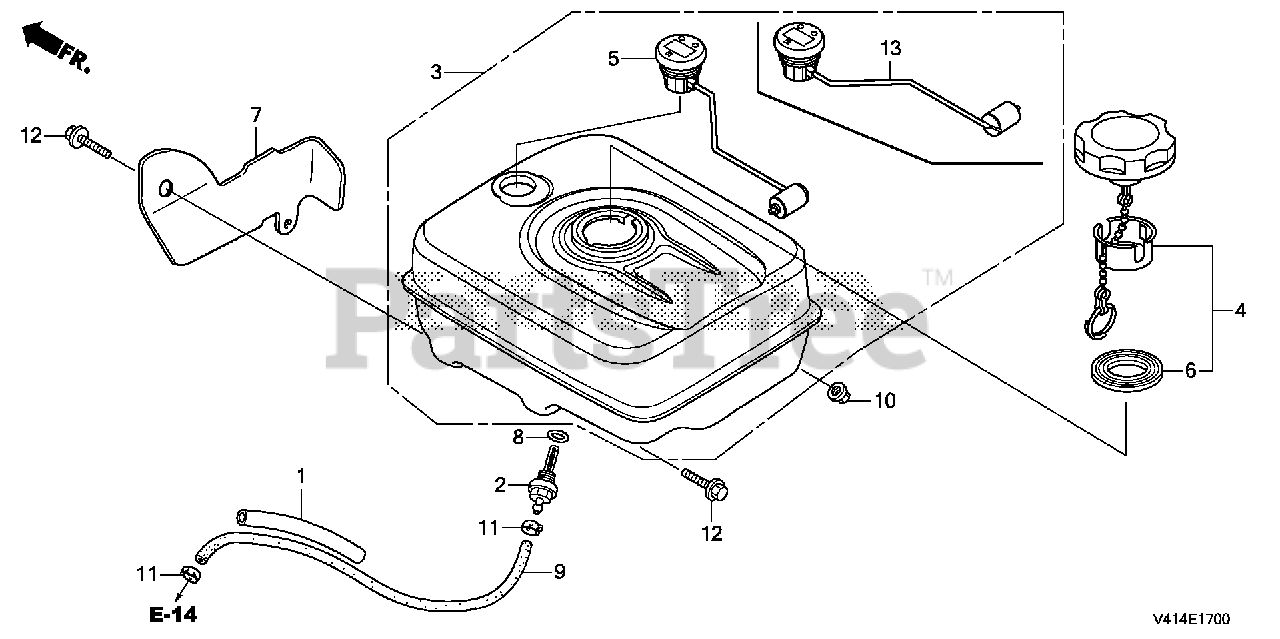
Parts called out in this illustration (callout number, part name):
1	RUBBER, SUPPORTER (107MM)
2	JOINT, FUEL TANK
3	TANK ASSY., FUEL *R280* (GAUGE) (POWER RED)
4	CAP, FUEL FILLER
5	GAUGE ASSY., FUEL
6	GASKET, FUEL FILLER CAP (39X62X3) (RADICON)
7	COVER, SNOW PLATE
8	O-RING (13.5X1.5) (ARAI)
8	O-RING (14MM) (NOK)
9	TUBE, FUEL (4.5X235) (FKM)
10	NUT, FLANGE (8MM)
11	CLAMP, TUBE (D8)
12	BOLT, FLANGE (8X28)
